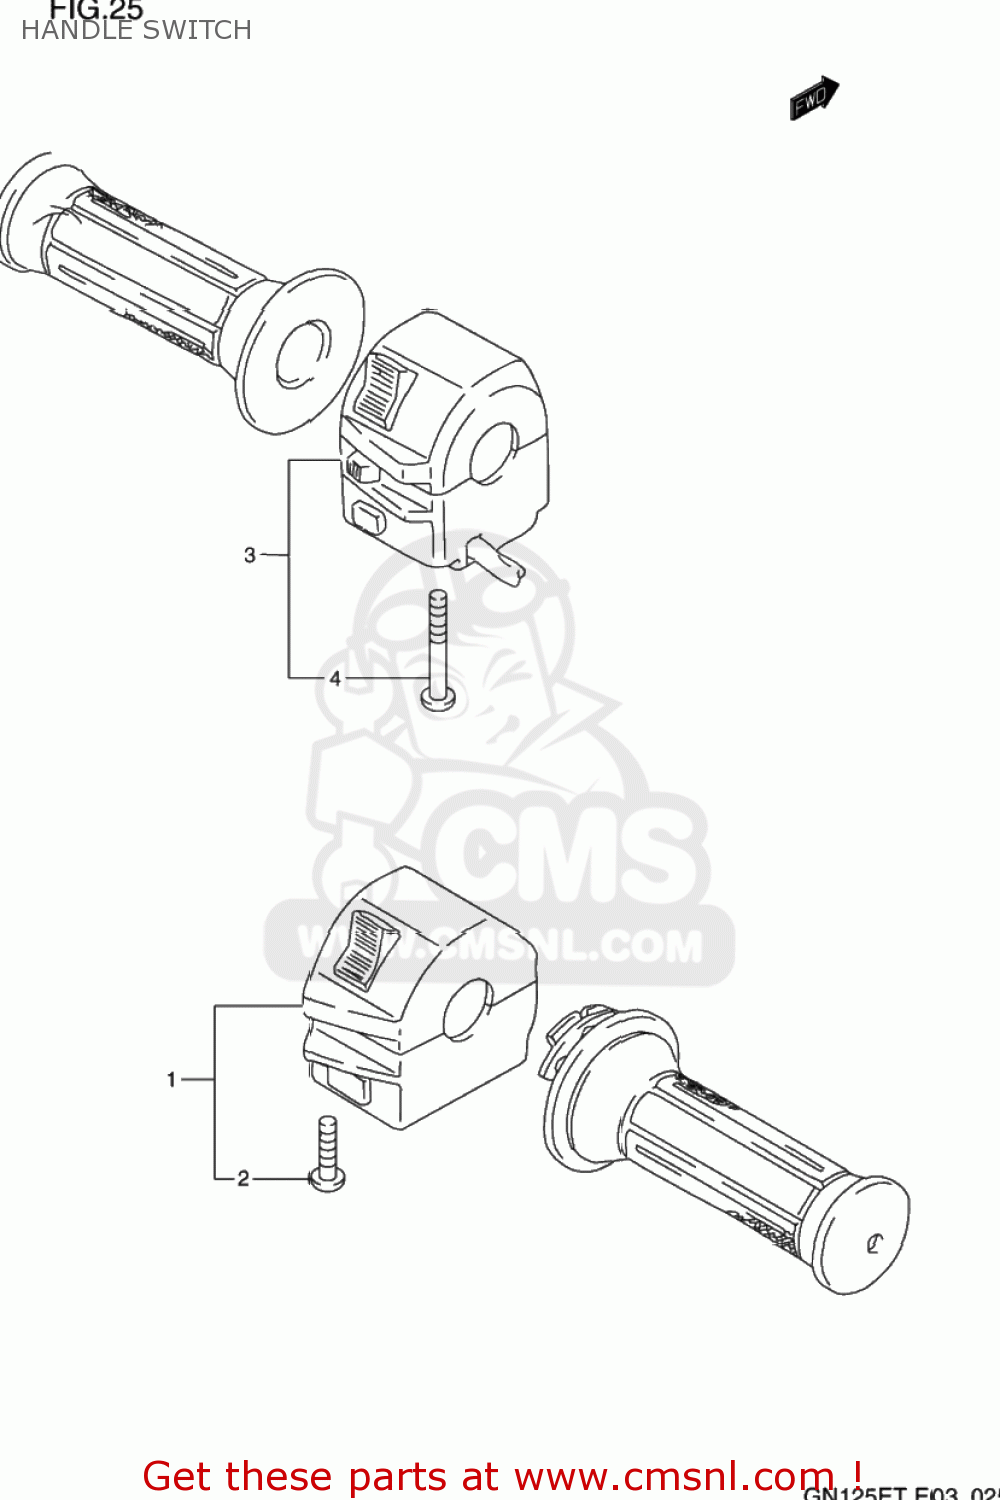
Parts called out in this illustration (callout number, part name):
1	SWITCH ASSEMBLY,HANDLE,RIGHT
2	SCREW 5X20
3	SWITCH ASSEMBLY,HANDLE,LEFT
4	SCREW
